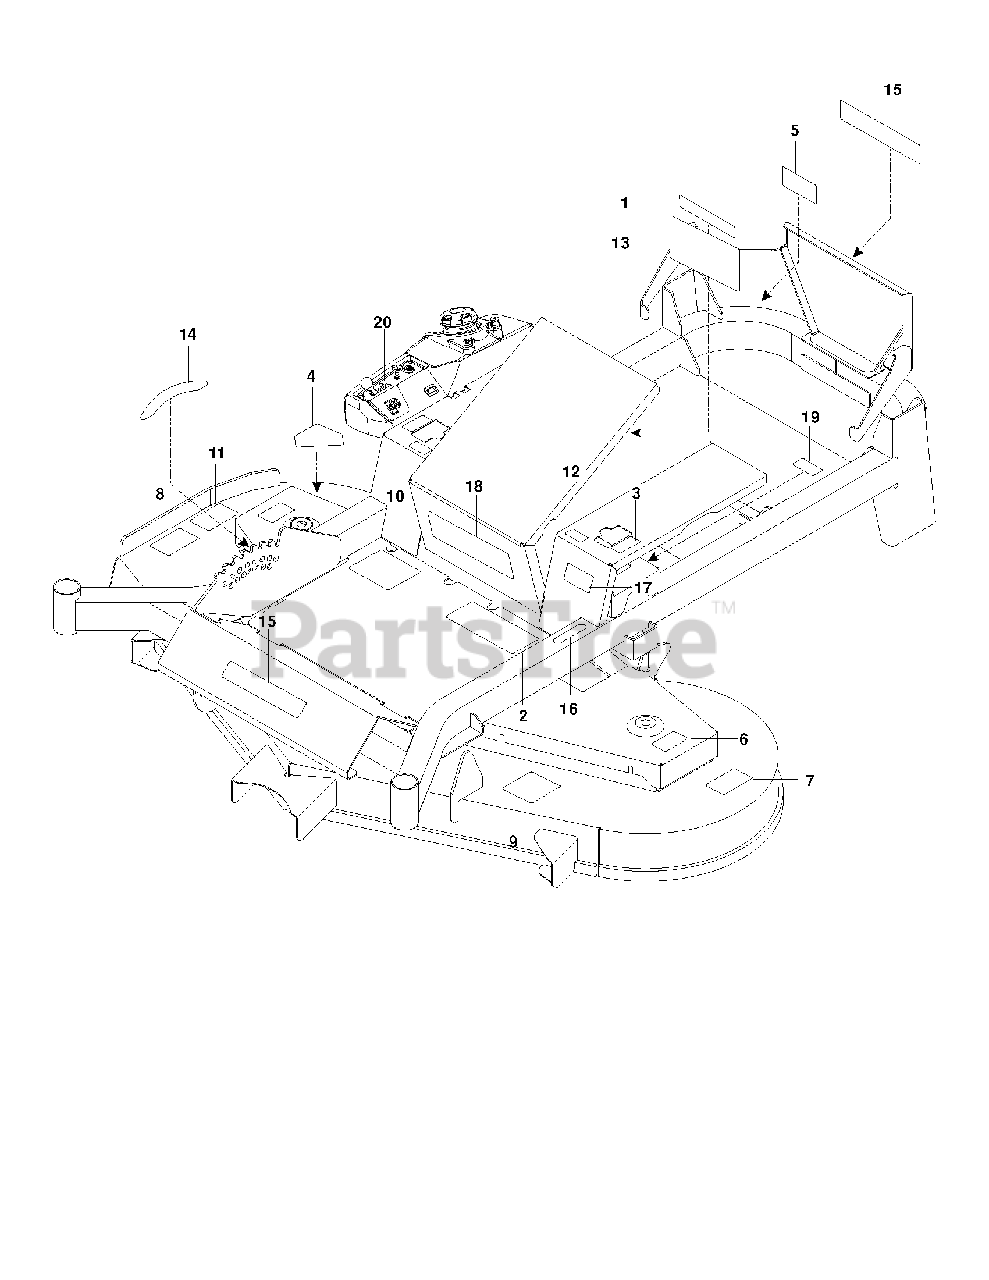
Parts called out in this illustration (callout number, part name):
2	DECAL, WARNING
3	DECAL, MOTION CONTROL
4	DECAL, CPSC
5	DECAL, BELT DRIVE
8	DECAL, EURO SEVERING
9	DECAL, BELT ROUTING
10	DECAL, WARNING
12	DECAL, TRACKING
13	DECAL, SERVICE
14	DECAL, HEIGHT 5"
16	DECAL, PARK BRAKE
17	DECAL, FLAG
19	DECAL, FUEL
